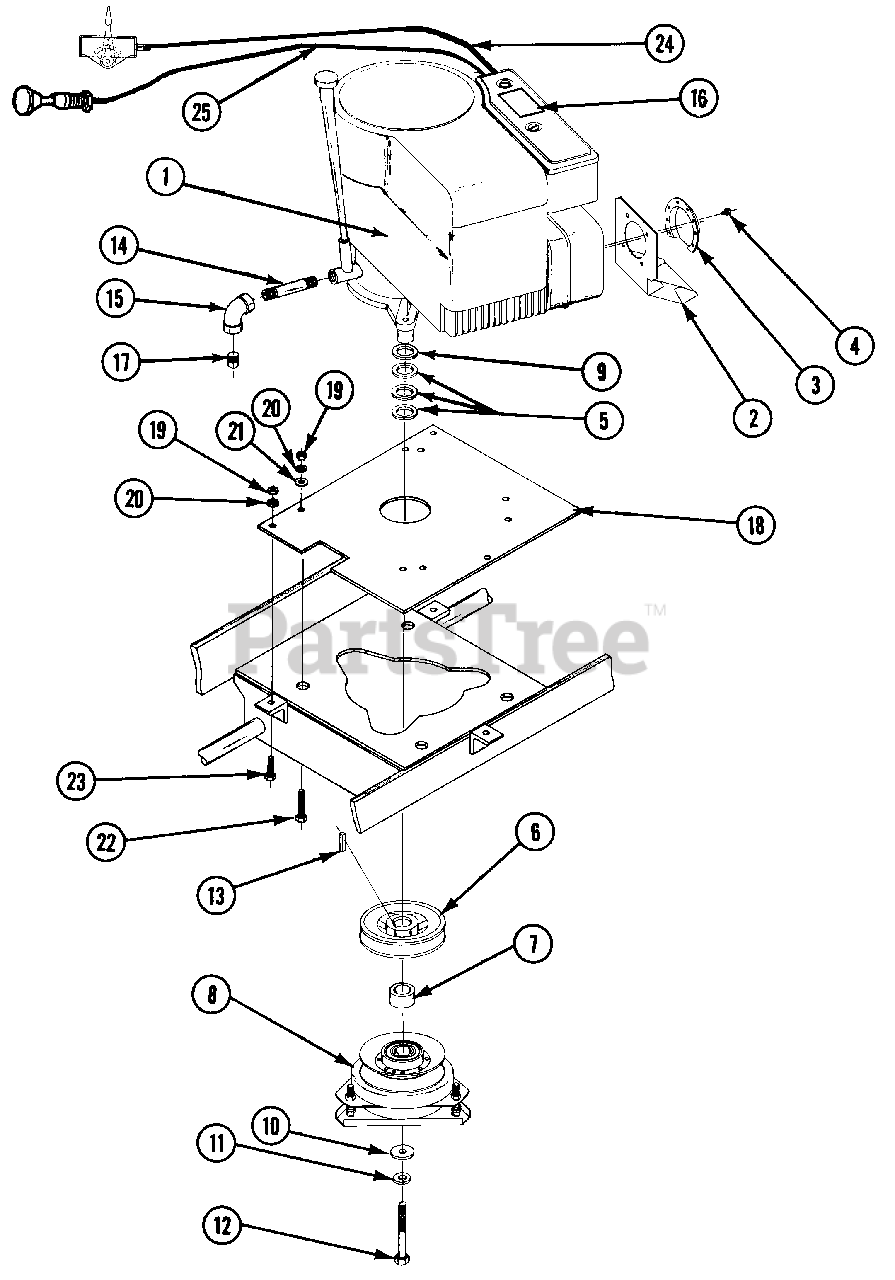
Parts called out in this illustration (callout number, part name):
1	ENGINE, 12 HP, GAS
2	EXHAUST DEFLECTOR
3	SIDEOUT DEFLECTOR
4	SCREW FOR DEFLECTOR
5	WASHER 1-1/2 OD X 1 ID X 1/8 THK
6	PULLEY BK50-1, 4" A PITCH
7	SPACER PULLEY/ELECTRIC CLUTCH
8	CLUTCH, ELECTRIC #5210-17
9	WASHER, 1-1/2 OD X 1" ID X 1/16 THK
10	WASHER, 15/32" ID
11	LOCKWASHER, 7/16 SPLIT SPRING
12	CAPSCREW, 7/16-20 X 3, GRADE 5
13	SQUARE KEY, 1/4" X 1"
14	NIPPLE, 3/8 X 3, SCH. 40, BLACK
15	ELBOWS 3/8, 90 DEGREES SCH. 40
16	DECALS "PERIODICALLY CLEAN DEBRIS"
17	3/8 PIPE PLUGS BLACK
18	MOTOR MOUNTING PLATE
19	NUTS 5/16-24 UNF, GRADE 5
20	LOCKWASHER, 5/16 HEAVY SPRING
21	WASHER FLATS STD, STEEL 5/16"
22	CAPSCREW, HEX, 5/16-24 X 1-1/2' GRADE 5
23	CAPSCREW, HEX, 5/16-24 X 1, GRADE 5
24	THROTTLE CABLE
25	CHOKE CABLE
